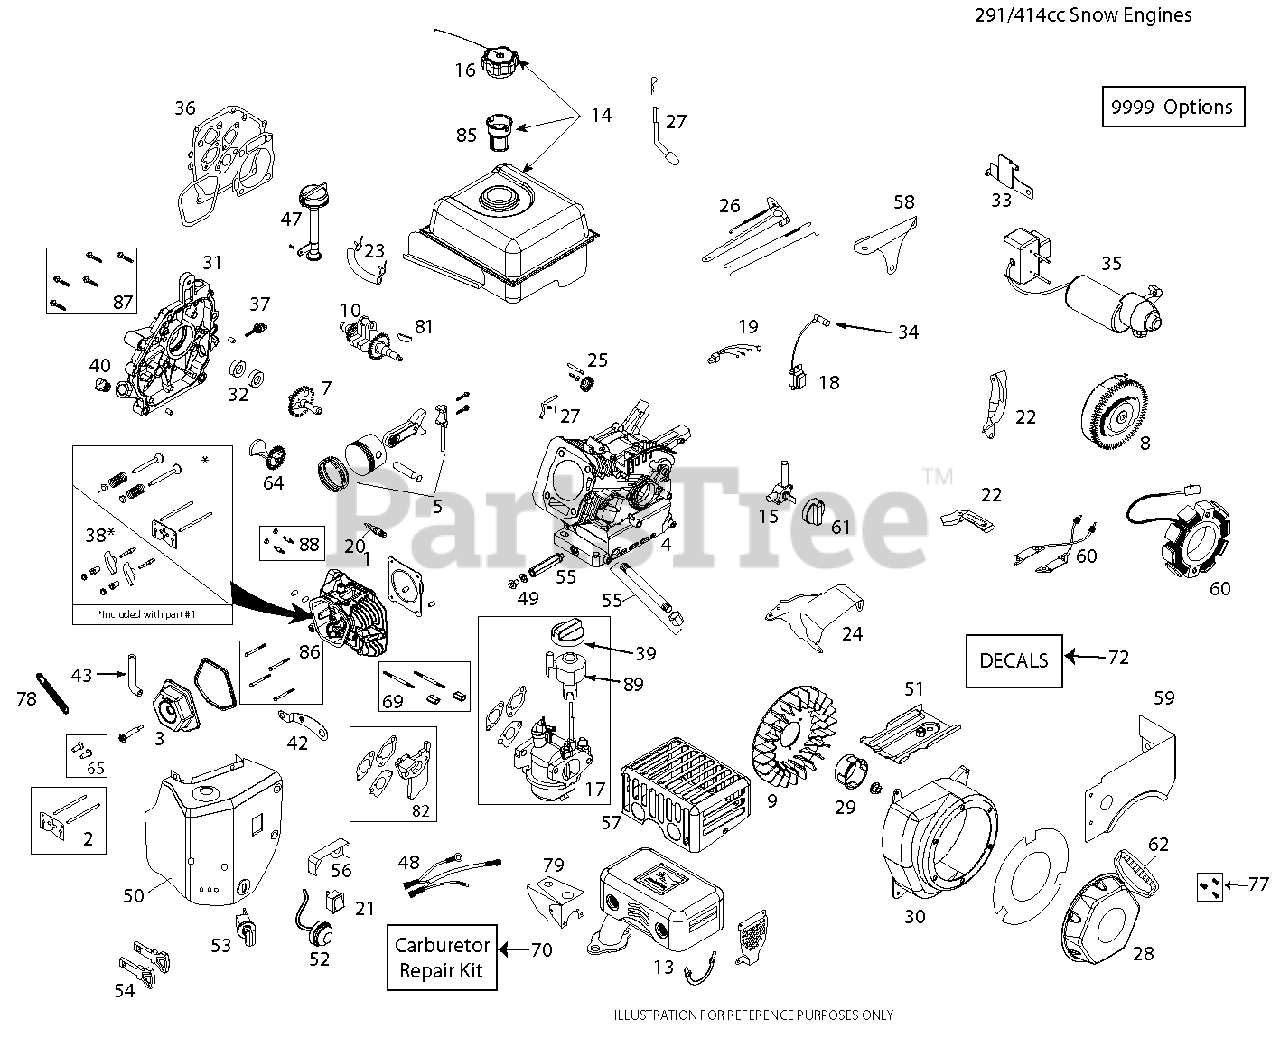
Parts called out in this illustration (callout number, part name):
1	CYLINDER.HEAD.ASSY(SK2911000)
2	PUSH ROD TAPPET KIT
3	VALVE.COVER.LCT.414CC.
4	CYLINDER ASSY SNO.LCT
5	PISTON.AND.ROD.ASSY(SK2911400)
7	CAMSHAFT.LCT.291CC
8	FLYWHEEL.EL.ST.SKSNO2401.1
9	FLYWHEEL.FAN
10	CRANKSHAFT LCT.SKSN2805.1
13	MUFFLER (SKSN2210.1)
14	FUEL TANK ASSY - SNOW (291CC)
15	FUEL.PETCOCK.SNOW(SKSN4900)
16	FUEL.TANK.CAP.SNOW(SKSN4301)
18	COIL.IGN.CDI.SKSN2403.1
20	SPARK.PLUG(SK2911550)
21	ON/OFF.SWITCH.SNOW(SKSN4403)
22	SHIELD.U/FYWHL.CHARG(SKSN4604)
23	FUEL HOSE KIT
24	TOP.SHIELD.LCT.
25	GOVERNOR.GEAR.ASSY(SK2912900)
26	GOVERNOR.ARM.ASSY.(SKSN2502)
27	GOVERNOR.SHAFT.(SK2913100)
28	RECOIL.START.ASSY.(SKSN2600)
29	STARTER.CUP.SMALLSNOW(SKSN2601
30	BLOWER HOUSING.BLK ES LCT 291
31	CRANKCASE.COVER.ASY(SK2913600)
32	OIL.SEAL.KIT(SK2913900)
33	SWITCHBOX BRACKET ES LCT 291 S
34	SPARK.PLUG.BOOT.SNW,SKSN4691.1
35	ELECTRIC.START.ASSY(SKSN2400.2
36	ENGINE.GASKET.KIT(SK2914300)
37	DIPSTK.OIL.BLK.LCTSK4143711.1
38	ROCKER ARM KIT
39	CHOKE.KNOW.SNOW(SKSN4500)
40	NONREMVABLE.OIL.PLUG(SK4143715
42	CDI.BOX.BRKT.SNOW(SKSN4402)
43	TUBE.BREATHER.LCT.219CC/414CC
47	TUBE OIL FILL KIT.LCT SKSN4950
48	WIRE.HARNESS(SKSN4406)
49	OIL.DRAIN.PLUG
50	HEATER.BOX.ASSY.SNOW(SKSN2100)
51	SHIELD.CYLINDER.SNOW(SK4141010
52	PRIMER.BULB.ASSY(SKSN4304)
53	KEY.SWITCH.ASSY.SNOW(SKSN4401)
54	KEY SET(2 KEYS) SKSN0407.1
55	OIL PIPE DRAIN EXTENDED.LCT SK
56	SHIELD.VAPOR(SKSN4606)
57	SHIELD.MUFFLER.
58	GOVERNOR.LINK.SHIELD(SKSN2501)
59	FUEL.TANK.SKIRT(SKSN2101)
60	ALTERN.60WATT.SKSN2402.1
61	FUEL KNOB-SNOW
62	HANDLE.RECOIL.DELUXE.LCT
65	TAPPET KIT.LCT.SK2911005.1
69	STUD.CARB.MOUTING.KIT.291CC
70	CARBURETTOR REPAIR KIT 291CC/4
77	BOLT.KIT.RECOIL.LCT.ALL.ENGINE
81	KEYS.FLYWHEEL.136/291CC.5PACK
82	SPACER.CARBURETOR.291CC.LCT
85	STRAINER.FUEL.TANK.LCT.208CC
86	KIT.BOLT.CYLINDER.HEAD.(4PC)
87	KIT.BOLT.CRANKCASE.COVER.291CC
88	STUD.MUFFLER.KIT.LCT
89	KNOB LCT.SKSN5325.1 SPEED
9999	HIGH.ALTITUDE.JET.(>6,000FT)
